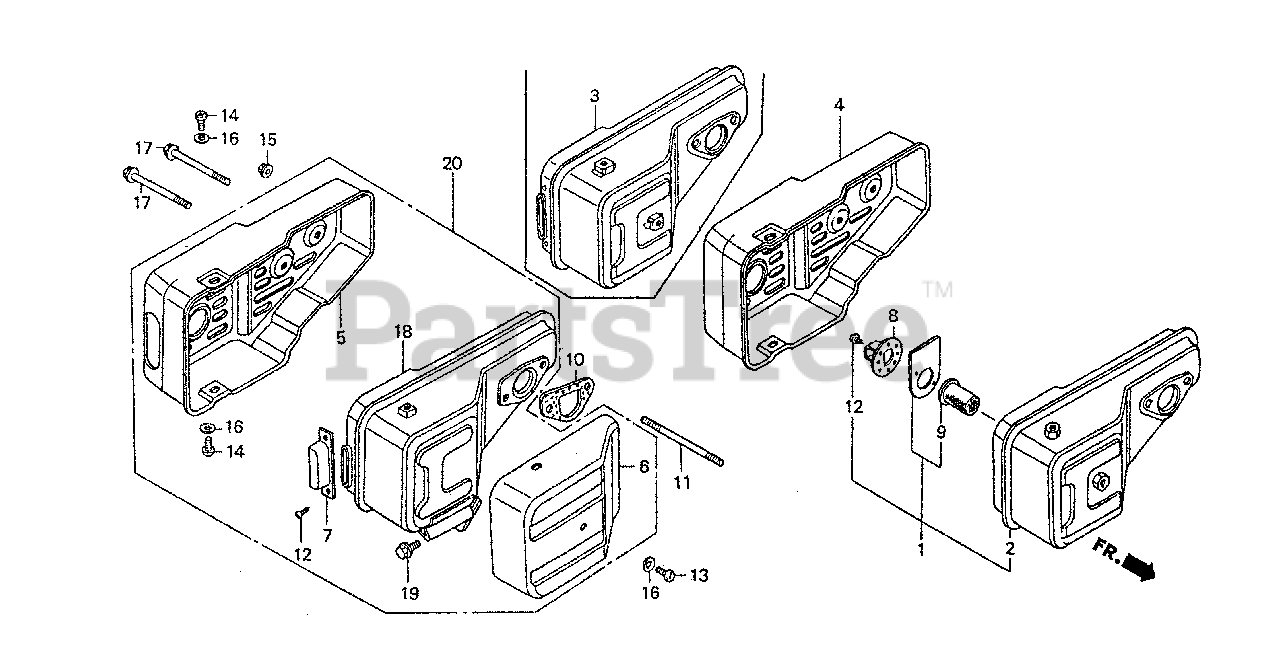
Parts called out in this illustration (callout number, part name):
3	MUFFLER (W/PROTECTOR)
5	PROTECTOR, MUFFLER
6	SEPARATOR, MUFFLER
10	GASKET, MUFFLER
11	BOLT, STUD (6X50)
14	SCREW, PAN (6X6)
15	NUT, FLANGE (6MM)
16	WASHER, PLAIN (6MM)
20	MUFFLER ASSY.
